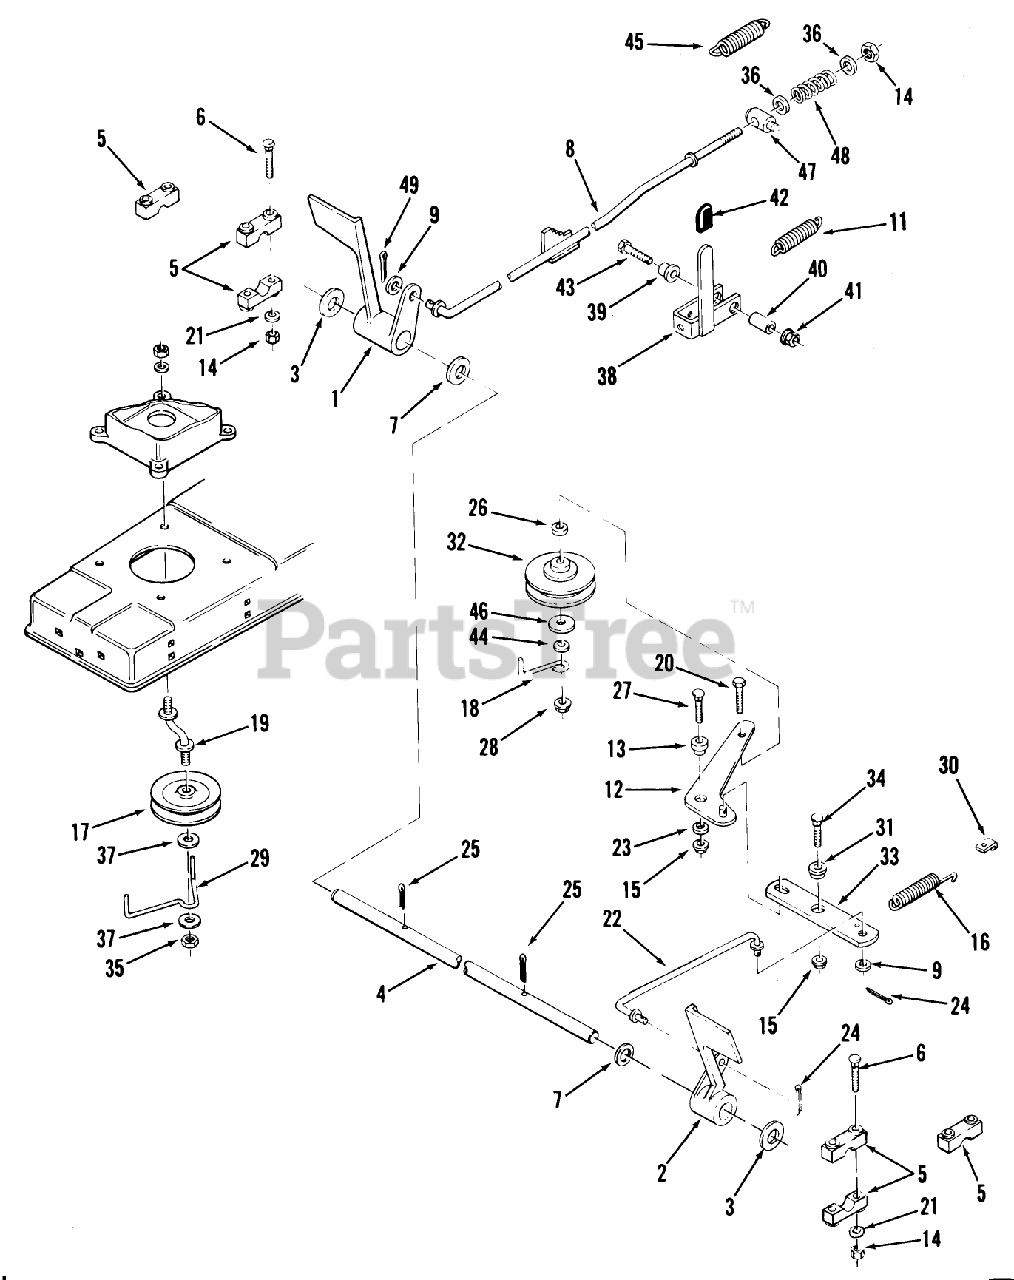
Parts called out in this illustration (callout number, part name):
1	PEDAL-BRAKE *R
3	WASHER-SPECIAL
9	WASHER 5/16 SAE
11	SPRING-EXTENSION
13	SPACER-IDLER ARM
16	SPRING
17	PULLEY-IDLER STATION
21	WASHER 5/16 SAE
22	ROD-CLUTCH *R
30	CLIP - SPRING
32	Pully-Idler
38	PAWL-HANDLE ASSY
39	SPACER
40	SPACER
42	GRIP
45	SPRING-EXTENSION
46	WASHER
47	TRUNNION-LIFT
49	Screw-Sem
